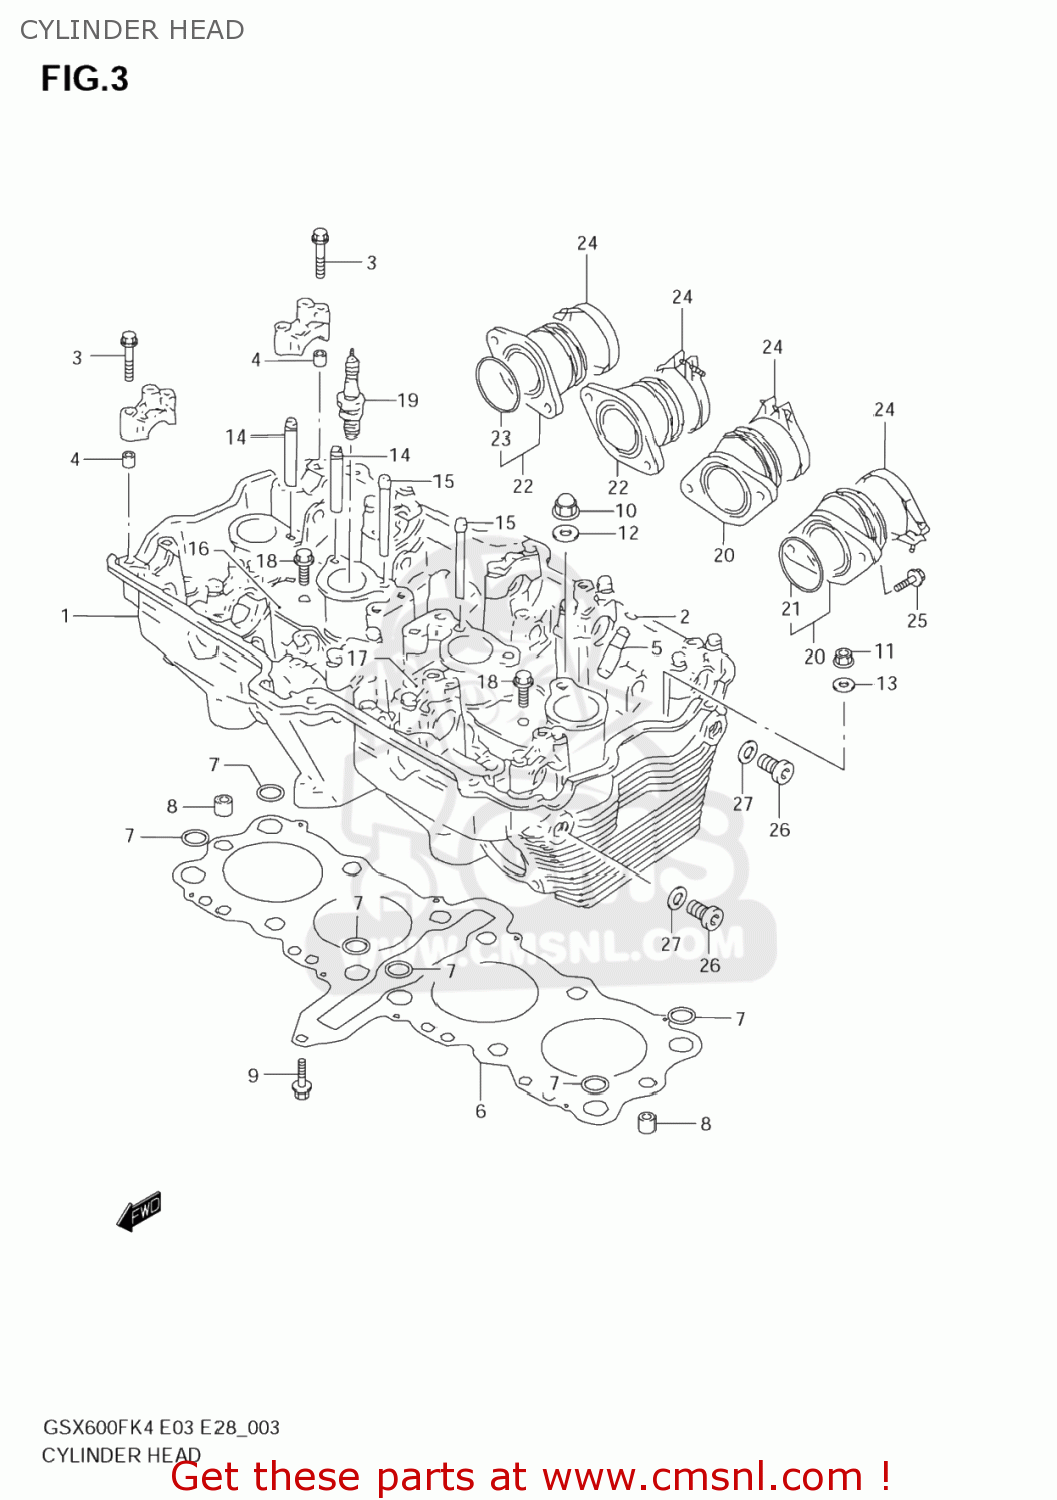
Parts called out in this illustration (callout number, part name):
1	HEAD ASSY,CYLINDER
2	RING,SNAP
3	BOLT(6X39)
4	PIN(6.2X8X11)
5	GUIDE,VALVE
6	GASKET,CYLINDER HEAD (NAS)
7	O RING(D:2.6,ID:12.1)
8	PIN
9	BOLT
10	NUT
11	NUT
12	GASKET(10.2X20X2).3 (NAS)
13	WASHER (10.5X22X2.3)
14	PIPE,OIL NO.1
15	PIPE,OIL NO.3
16	PLATE,OIL PIPE,R
17	PLATE,OIL PIPE,L
18	BOLT
19	PLUG,SPARK(CR9EK)
20	PIPE ASSY,INTAKE NO.1
21	O RING(D:2.4,ID:39.7)
22	PIPE ASSY,INTAKE NO.3
23	O RING(D:2.4,ID:39.7)
24	CLAMP
25	BOLT MAGNETO S
26	PLUG
27	GASKET(13.8X18.8X4.8) (NAS)
